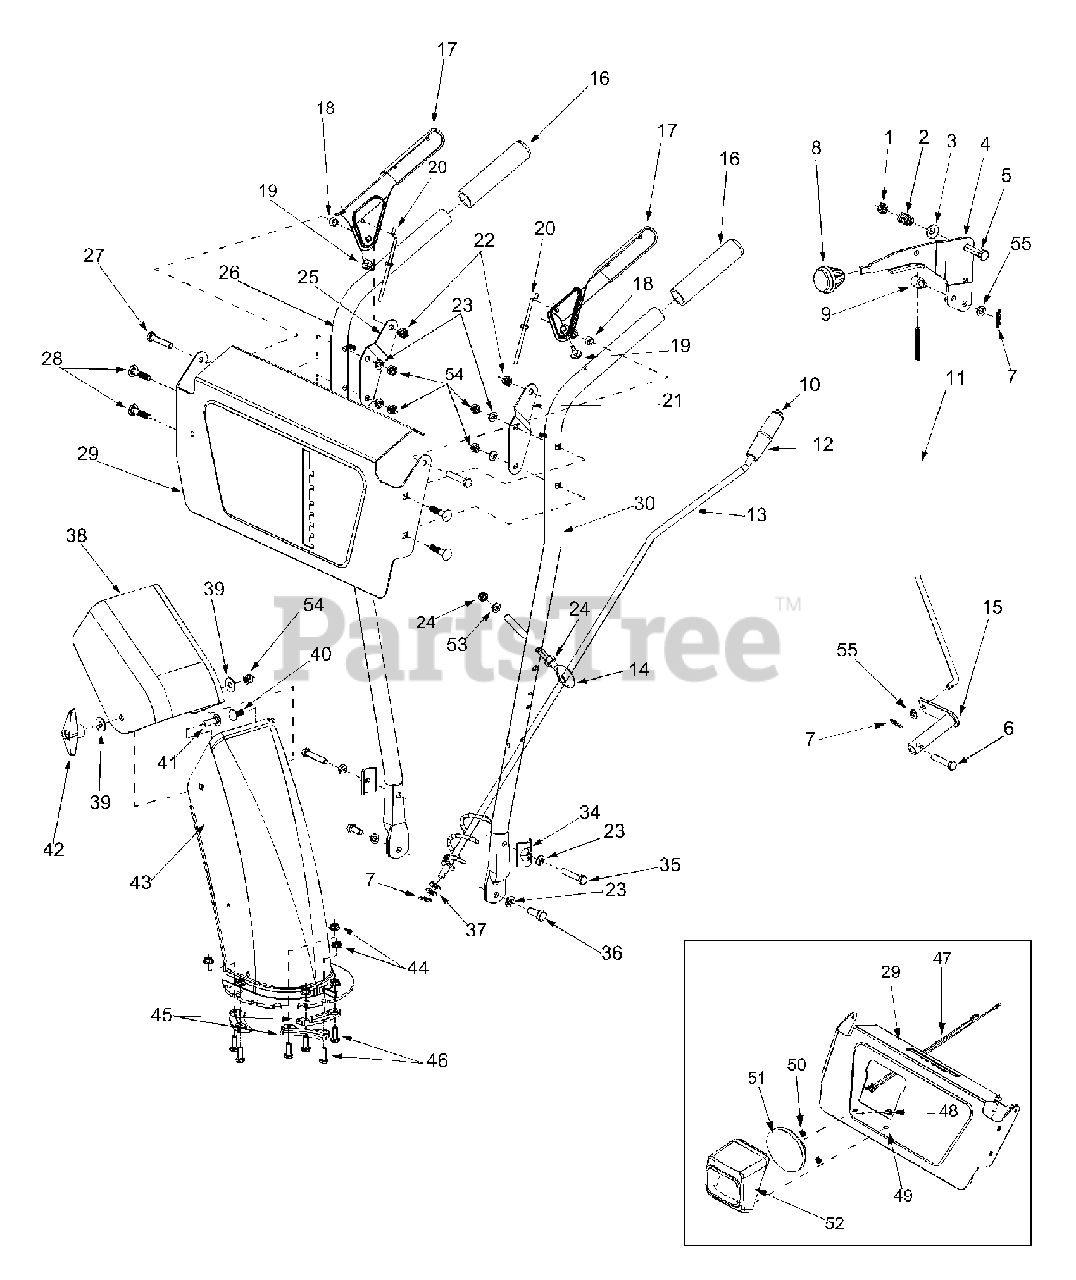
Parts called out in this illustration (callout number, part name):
1	Jam Lock Nut 3/8-24
2	Compression Spring
3	Bell Washer
6	Tap Screw 1/4-20
7	Cotter Pin
8	Shift Knob
9	Ferrule
10	Push Cap
11	Shift Rod
12	Chute Knob
13	Chute Directional Control
14	Eyebolt
17	Clutch Lever Assy LH
18	Spacer
19	Rubber Bumper
20	"Z" Fittings For Control Cables
23	Lock Washer 5/16
24	Hex Nut 5/16-18
28	Carriage Bolt 5/16-18 x 1.50
35	Hex Cap Screw 5/16-18 x 2.0
36	Hex Cap Screw 5/16-18 x .75
37	Flat Washer
38	Upper Chute
39	5/16 Washer
40	Carriage Bolt 5/16-18 x .75
41	Carriage Screw 5/16-18 x 1.0
43	Lower Chute
44	Hex Lock Nut 1/4-20
45	Flange Keeper
46	Hex Cap Screw 1/4-20 x .75
47	Round Light Harness
48	Hex Tap Screw 1/4-20 x .625
49	Hex Screw
50	Hex Nut
51	Headlight 18 Watts
52	Headlight Cover
53	Bell Washer
54	Hex P\atch Nut 5/16-18
55	Flat Washer .344 ID x .688 OD
